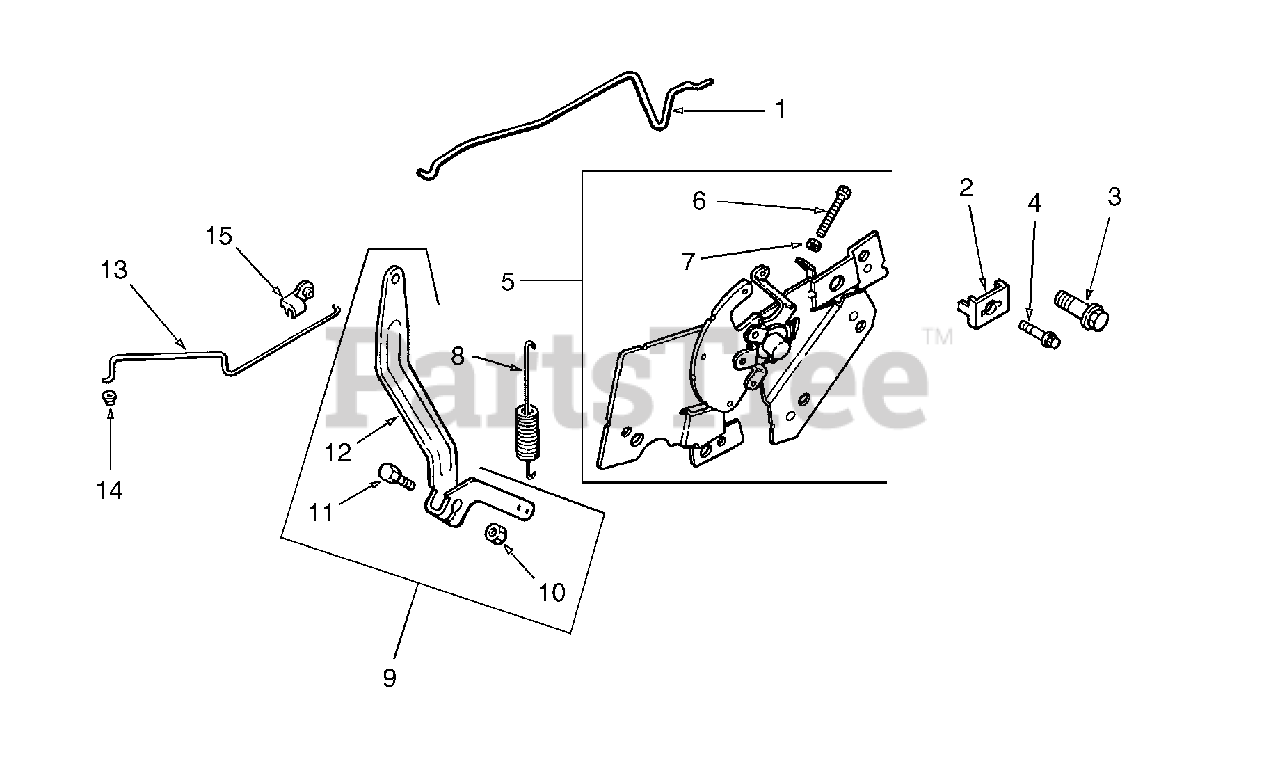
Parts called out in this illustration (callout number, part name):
1	Linkage, Choke
2	Clamp, Cable
3	Screw, Lobed Socket, M6 x 1.0 x 20
4	Screw, Hex Flange, M5 x 0.8 x 16
5	Control Assembly, Speed
6	Screw, Hex Cap, M4 x 0.7 x 30
7	Nut, Hex, M4 x 0.7
8	Spring, Governor
9	Kit, Governor Lever
10	Nut, Hex Flange
11	Bolt, Round Head
12	Lever, Governor
13	Linkage, Throttle
14	Bushing, Linkage Retaining
15	Bushing, Linkage Retaining
